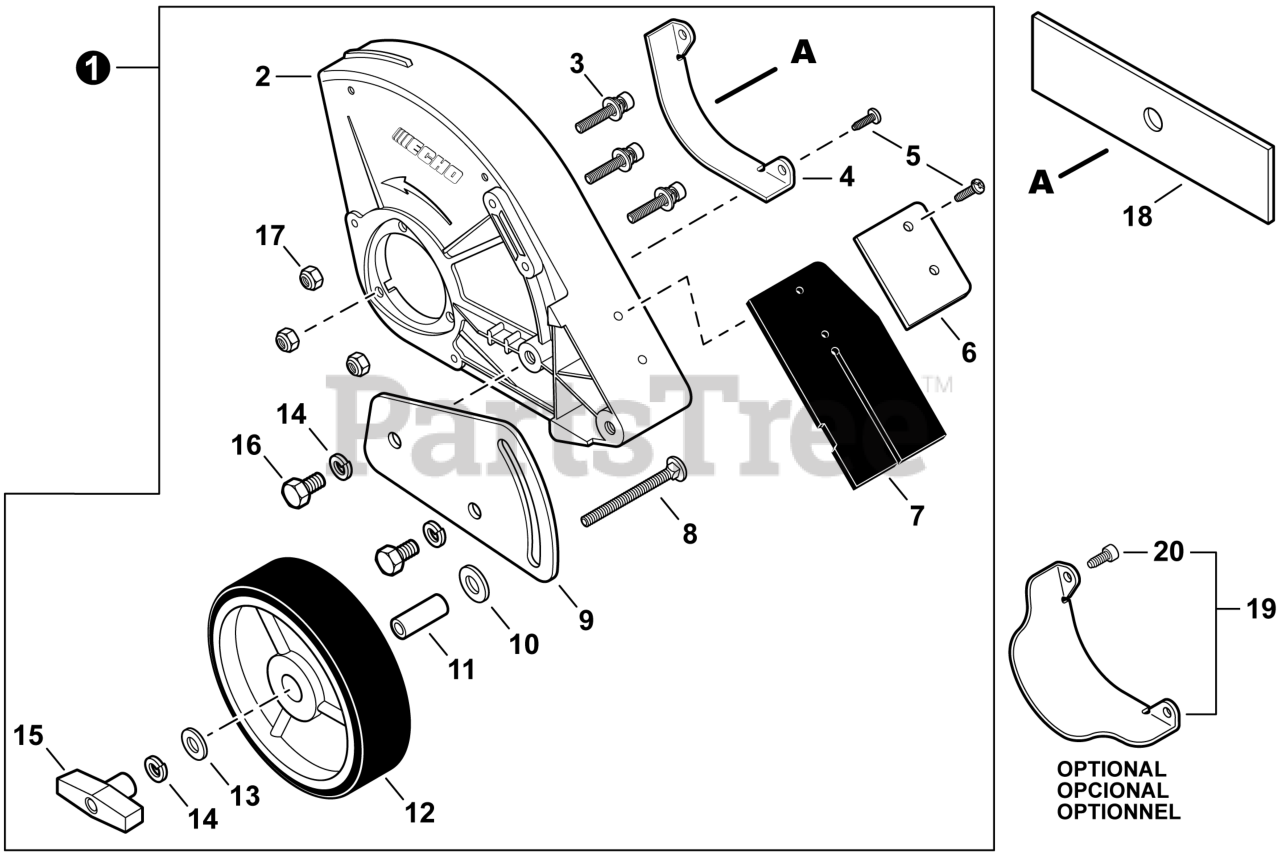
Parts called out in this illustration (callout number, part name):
1	SHIELD KIT, EDGER
2	SHIELD, BLADE
3	BOLT 5x25
4	GUARD, SHIELD
5	SCREW 4x12
6	PLATE, FLAP
7	FLAP, DEBRIS
8	BOLT 5/16"-18x2-1/2"
9	BRACKET, WHEEL
10	WASHER M10
11	COLLAR 12
12	WHEEL
13	WASHER 8
14	WASHER, SPRING 8
15	KNOB, FASTENER
16	BOLT 8x14
17	NUT, LOCK M5
18	BLADE - 2 PK
19	GUARD KIT, SHIELD
20	SCREW 4x12
